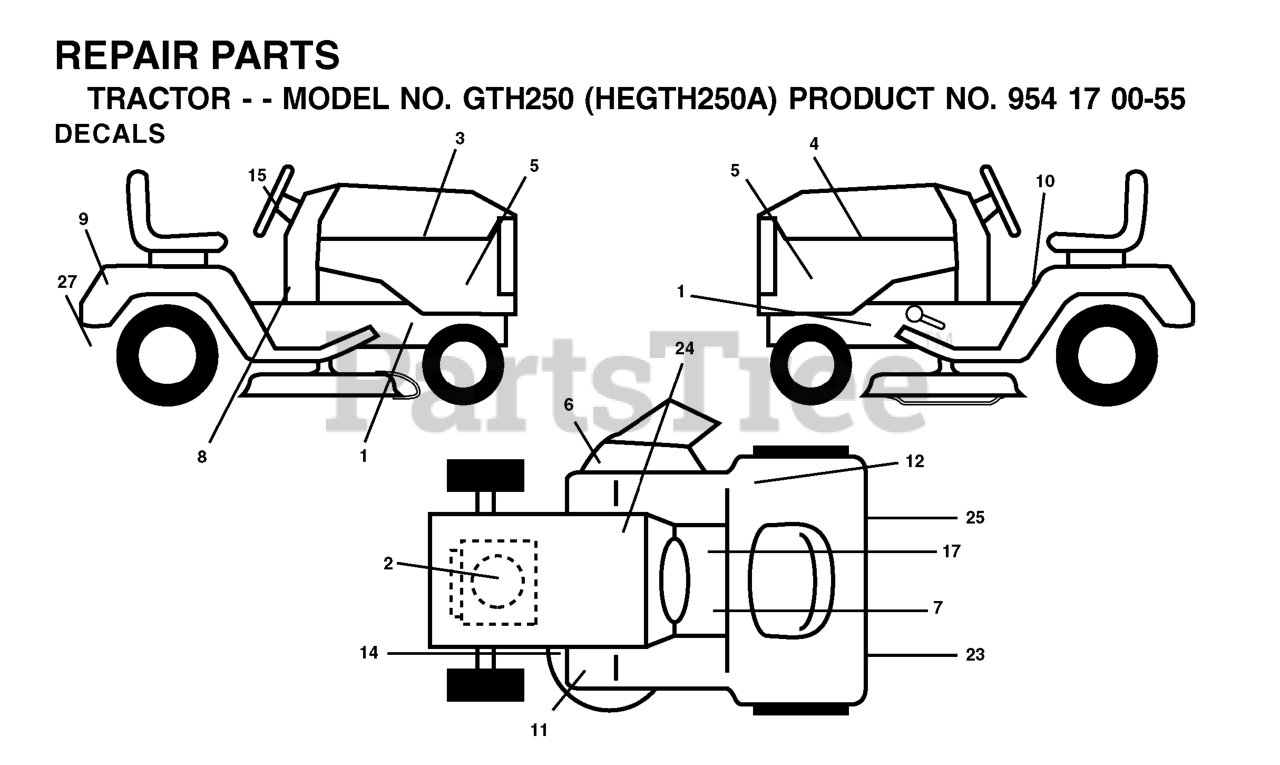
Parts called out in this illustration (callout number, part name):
2	Decal, Engine
3	Decal, Hood, RH
4	Decal, Hood, LH
5	DECAL PNL SIDE
6	DECAL MOWER CUT/FINGER
8	Decal, Dash
9	DECAL, FENDER
10	DECAL READ OWNER'S MAN SYMS
11	Decal, Foot Rest
14	DECAL V-BELT SCHEMATIC
15	DECAL.WHEEL.STEERING.HUSQ.PERM
17	DECAL PARK BRAKE
23	REFLECTOR, LH
24	DECAL BTRY SYMBOLS
25	REFLECTOR, RH
27	DECAL.BYPASS.FENDER.CRD.LT.YT
